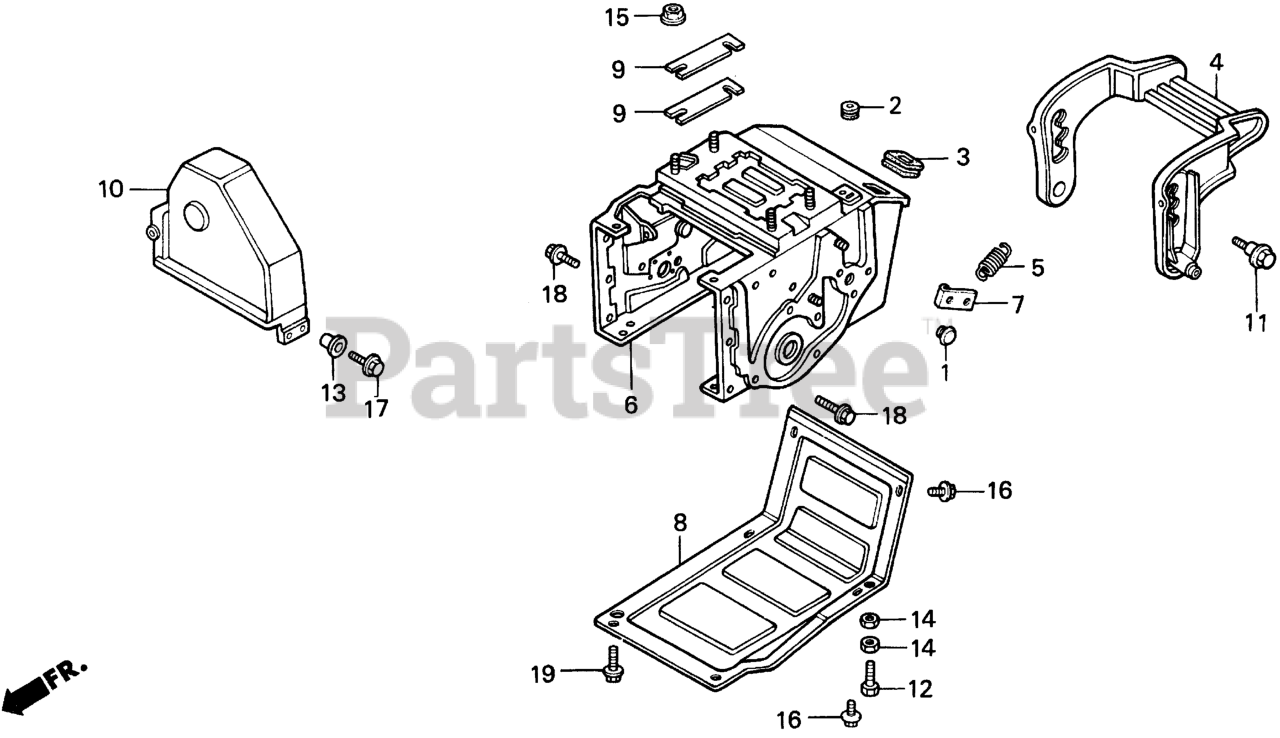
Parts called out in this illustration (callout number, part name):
1	GROMMET, GUIDE ROLLER (NOT AVAILABLE)
2	GROMMET A, TUBE
3	SEAL, CHANGE ROD
4	PLATE, HEIGHT ADJUSTING (NOT AVAILABLE)
5	SPRING, HEIGHT ADJUSTING
6	BED, ENGINE
7	HOOK, SPRING (NOT AVAILABLE)
8	COVER (LOWER) (NOT AVAILABLE)
9	SPACER, MOUNTING
10	COVER, BELT (NOT AVAILABLE)
11	BOLT, HEIGHT ADJUST SETTING
12	BOLT, ADJUSTING
13	WASHER, CHAIN CASE SETTING
14	NUT,HEX 8MM
15	NUT, FLANGE (10MM)
16	BOLT, FLANGE (6X10)
17	BOLT, FLANGE (6X16) Use from Engine SN 2056820.
18	BOLT, FLANGE (8X16) Use from Engine SN 1000016.
19	BOLT, FLANGE (8X40) Use up to Engine SN 1003236.
